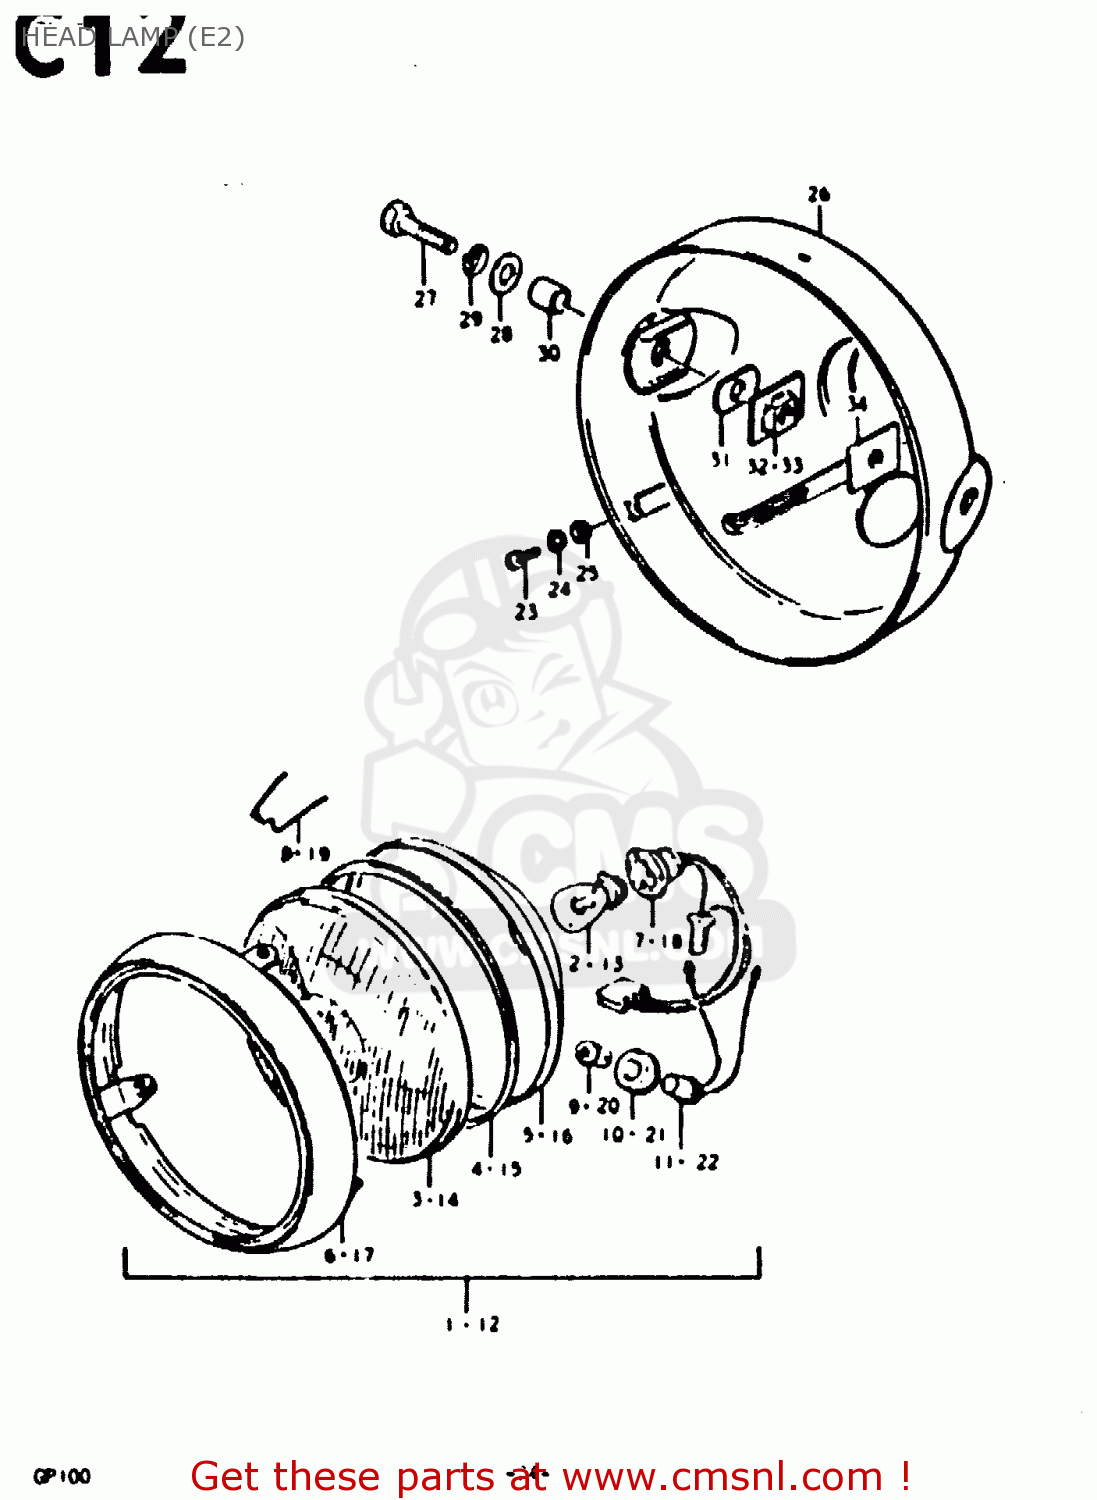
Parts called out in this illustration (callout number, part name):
1	HEADLAMP ASSY
2	BULB
3	LENS
4	GASKET (NAS)
5	REFLECTOR
6	RIM
7	SOCKET
8	SPRING
9	BULB(6V/3W)
10	SEAL,PARKING BULB
11	SOCKET, PARKING LAMP
23	SCREW
24	LOCK WASHER
25	WASHER
26	HOUSING,HEADLAMP
27	BOLT
28	WASHER
29	LOCK WASHER
30	SPACER (8.8X12X7)
31	CUSHION
32	PLATE,HEADLAMP HOUSING
